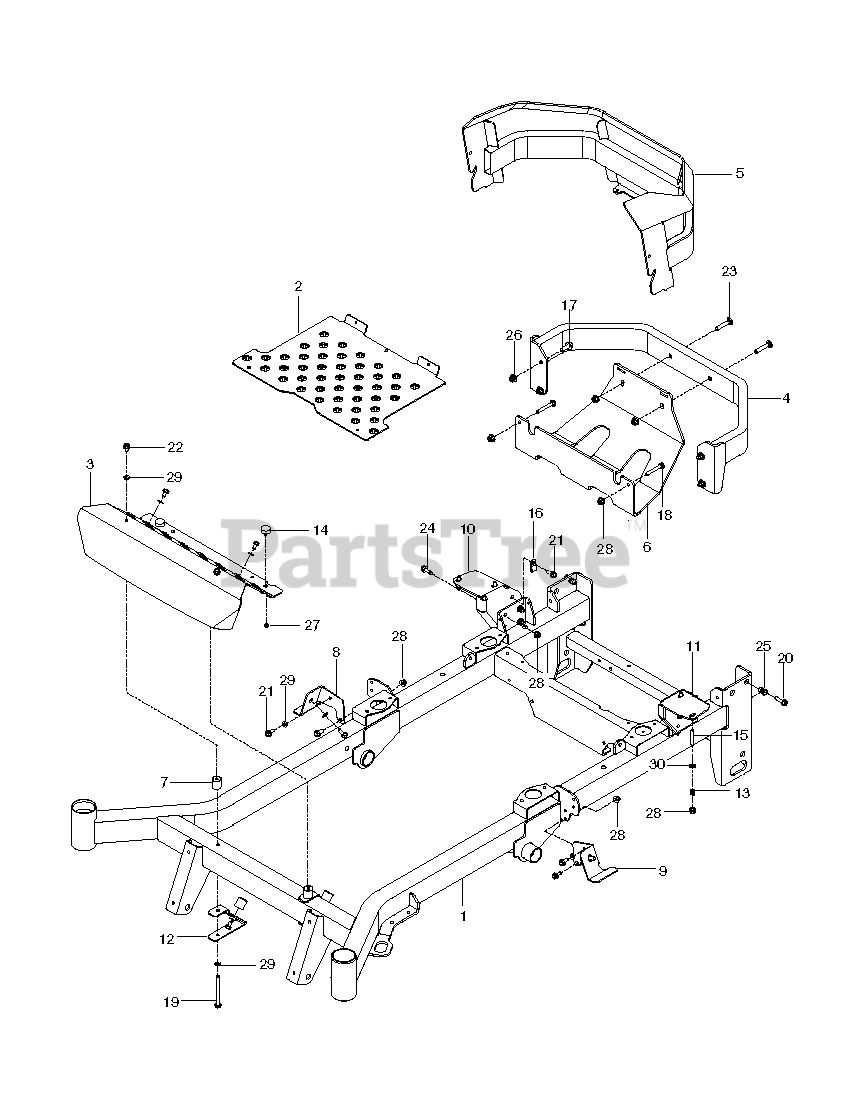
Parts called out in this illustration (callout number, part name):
1	FRAME W/DECALS, PZ
2	PLATE, FLOOR PAN, OR
3	PLATE, FOOT REST, OR
4	BUMPER.REAR.ORANGE
5	GUARD, REAR, GRAY
6	PLATE, SKID GRAY
7	MOUNT, F/F INSERT
8	MOUNT, RT TANK, BLK
9	MOUNT, LT TANK, BLK
10	MOUNT, TANK, RT-BLK
11	MOUNT, TANK, LT-BLK
12	BRACKET, REST MOUNT
14	BUMPER, 1/4-20 STUD, 1/4
15	STUD, 5/16C
16	DOUBLE TUBE CLAMP
17	HHFS 3/8-16 X 1 GRD 5 ZD
18	HHFS 5/16-18 X 2.25 GD 5
19	HHFS 5/16-18 X 3 3/4
20	HHFS 5/16-18 X 1.25 TPBLT GD 5
21	HHFS 5/16-18 X 3/4
22	SCR 5/16-18 X 1/2 SELFTAP ZN
23	RHSNB 3/8C X 2
24	RP BLT 5/16-18 X 1 THRD FORM D
25	NUTSERT 5/16-18 THICK GRIP
26	NUT 3/8-16 HEX FLG NYLOC ZD
27	JAM NUT 1/4C (2 2 PW01)
28	5/16-18 NYLOC FLANGE NUT
29	WASH 5/16 DISC SPRING ZD
30	FLAT WASHER 5/16 SAE
